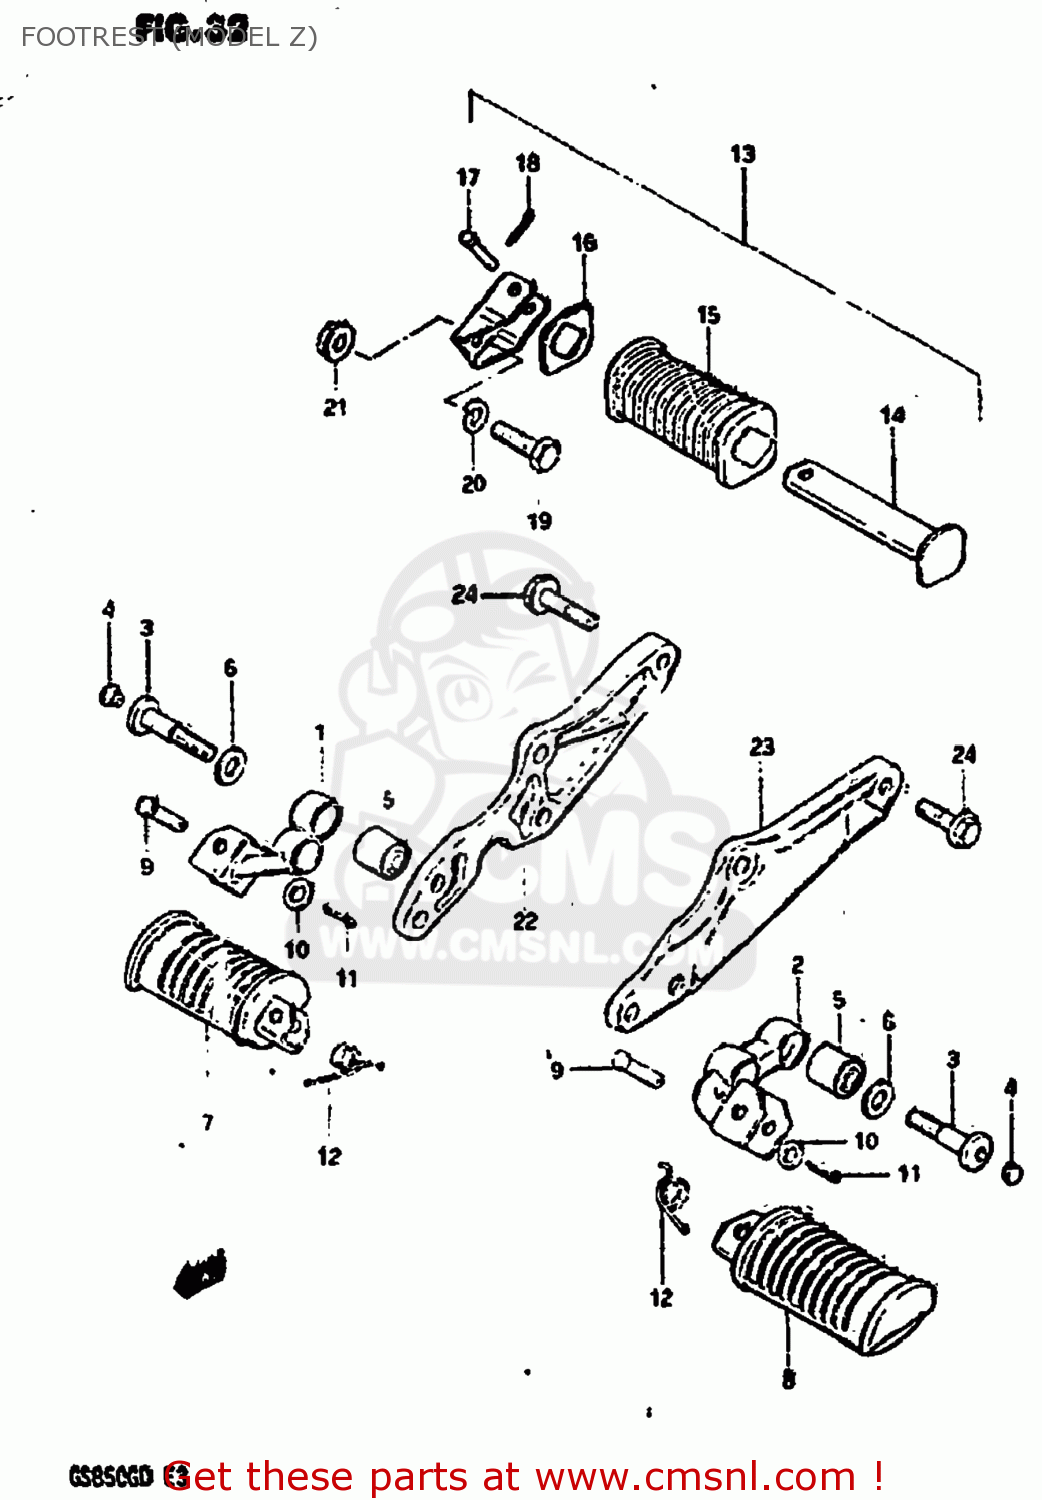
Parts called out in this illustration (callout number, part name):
1	BAR,FRONT FOOTREST,RIGHT
2	BAR,FRONT FOOTREST,LEFT
3	BOLT(10X50)
4	CAP
5	BUSH
6	WASHER
7	RUBBER,PILLION FOOTREST,R
8	RUBBER,PILLION FOOTREST,L
9	PIN
10	WASHER
11	PIN 20X20
12	SPRING
13	FOOTREST ASSEMBLY,REAR,LEFT
14	BAR,REAR FOOTREST,LEFT
15	RUBBER,PILLION FOOTREST
16	WASHER,FOOTREST RUBBER
17	PIN
18	PIN
19	BOLT,M10X1.25X
20	LOCK WASHER
21	NUT
22	BRACKET,MUFFLER,RIGHT
23	BRACKET,MUFFLER,LEFT
24	BOLT
